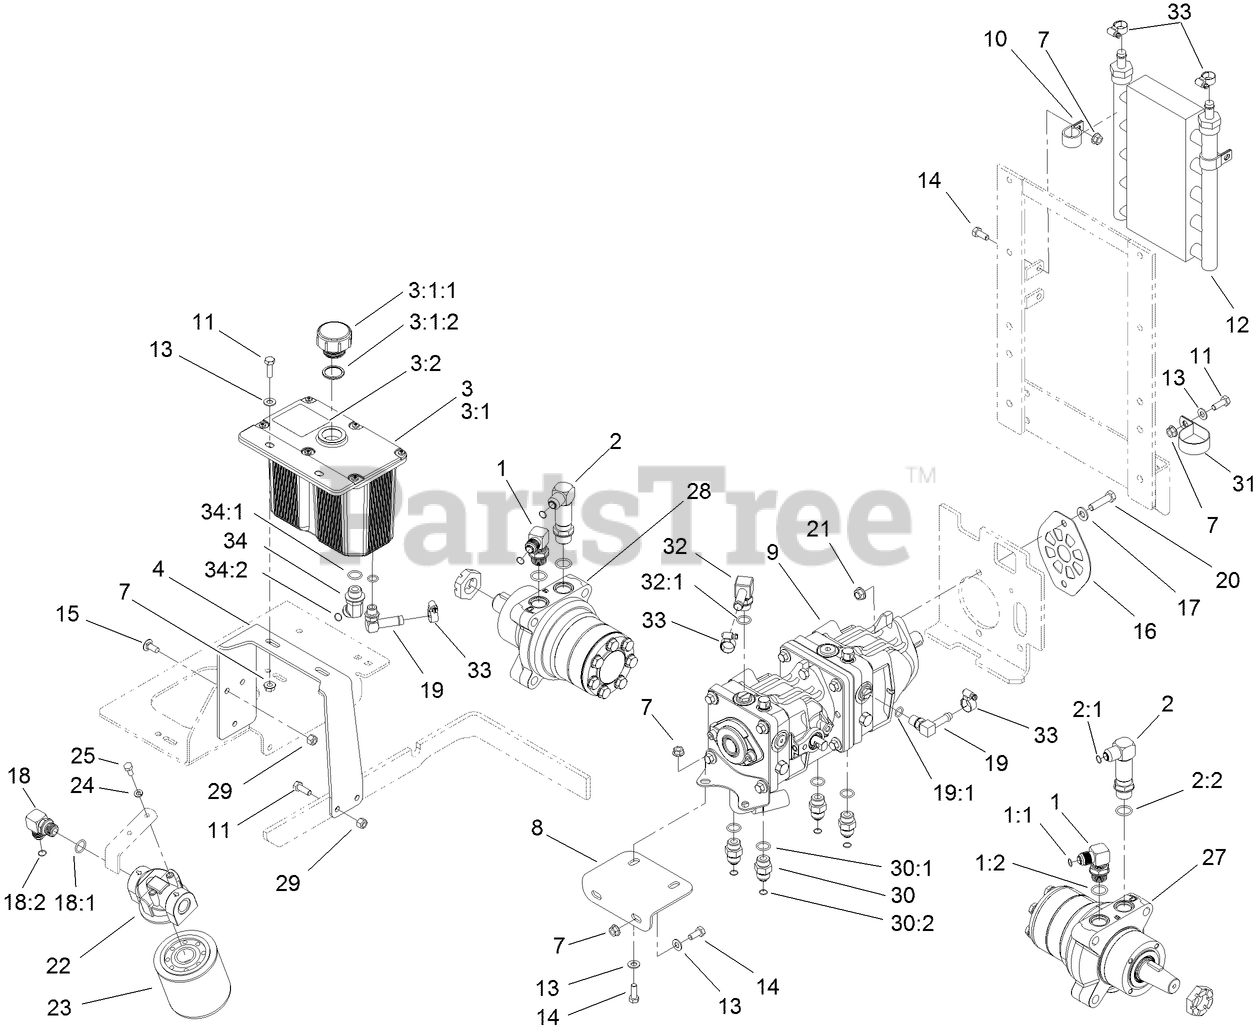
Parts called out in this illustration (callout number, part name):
1	FITTING-HYD, 90 DEG
1:1	O-Ring
1:2	O-RING
2	FITTING-ELBOW-90
2:1	O-Ring
2:2	O-RING
3	HYDRAULIC TANK ASM
3:1	TANK-HYDRAULIC
3:1:1	CAP-RESERVOIR, HYD
3:1:2	GASKET-CAP
3:2	DECAL-WARNING
4	BRACKET-TANK, HYDRAULIC
7	NUT-HF
8	BRACKET-PUMP, FRONT
9	TANDEM PUMP ASM
10	R-CLAMP
11	SCREW-HH
12	COOLER-OIL, HYDRO
13	WASHER-PLAIN
14	SCREW-HH
15	SCREW-CARR
16	PLATE-SHIELD, PUMP
17	WASHER-FLAT
18	FITTING-90 DEG
18:1	O-RING
18:2	O-Ring
19	FITTING-ELBOW, 90
19:1	O-RING
20	SCREW-HH
21	NUT-HHF, WHIZ
22	HEAD-FILTER
23	CARTRIDGE-FILTER, OIL
24	WASHER-LOCK
25	SCREW-HH
27	HYD MOTOR ASM (CCW)
28	HYD MOTOR ASM (CW)
29	NUT-LOCK, NI
30	FITTING-STRAIGHT
30:1	O-RING
30:2	O-Ring
31	CLAMP-R
32	FITTING-ELBOW, 90 DEG
32:1	O-RING
33	CLAMP-HOSE
34	FITTING-HYD, 45 DEG
34:1	O-RING
34:2	O-Ring
